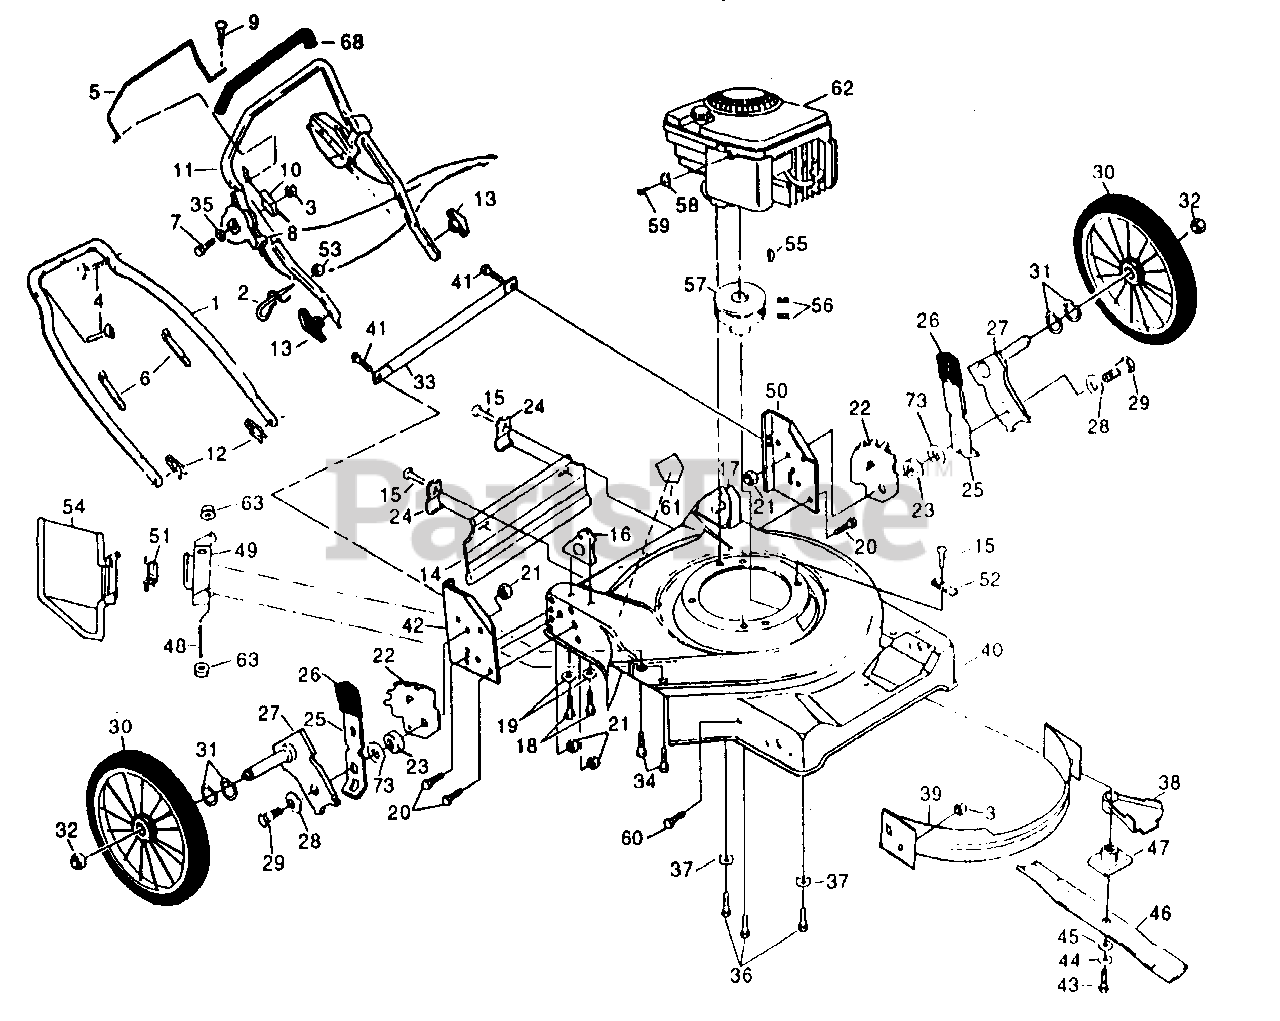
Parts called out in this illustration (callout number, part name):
1	Lower Handle (AYP part number)
2	Rope Guide
3	Locknut 1/4-20 (AYP part number)
4	Handle Bolt (AYP part number)
5	Control Bar (AYP part number)
6	Wire Tie (AYP part number)
7	Machine Screw 1/4-20 x 2-1/4 (AYP part number)
8	Throttle Control
9	Pan Head Hi/Lo Screw #10-16 x .63 (AYP part number)
10	Engine Zone Cable
11	Upper Handle (AYP part number)
12	Hairpin Cotter (AYP part number)
13	Handle Knob (AYP part number)
14	Rear Skirt (AYP part number)
15	Hex Head Screw #10 (AYP part number)
16	Handle Bracket Assembly (Right) (AYP part number)
17	Handle Bracket Assembly (Left) (AYP part number)
18	Screw 5/16-18 x 3/4 (AYP part number)
19	Washer (AYP part number)
20	Bolt, Hex Head 3/8-16 x 3/4 (AYP part number)
21	Locknut (AYP part number)
22	Wheel Adjusting Bracket (R.R.) (AYP part number)
23	Spacer (AYP part number)
24	Skirt Bracket (AYP part number)
25	Selector Spring (AYP part number)
26	Selector Knob
27	Axle Arm Assembly (AYP part number)
28	Rear Spring Washer (AYP part number)
29	Shoulder Bolt 3/8-16 (AYP part number)
30	Wheel & Tire Assembly (Rear) (AYP part number)
31	Wave Washer (AYP part number)
32	Nut (AYP part number)
33	Rod Support (AYP part number)
34	Hex Head Thread Rolling Screw w/Sems 1/4-20 x 3 (AYP part number)
35	Flat Washer (AYP part number)
36	Thread Rolling Screw 3/8-16 x 1 (AYP part number)
37	Engine Washer (AYP part number)
38	Debris Shield
39	Front Baffle (AYP part number)
40	Mower Housing Kit (Inc. 61)
41	Screw (AYP part number)
42	Wheel Support Bracket R.H. (AYP part number)
43	Hex Head Screw 3/8-24 x 1-3/8 Gr. 8
44	Helical Washer 3/8 (AYP part number)
45	Hardened Washer (AYP part number)
46	22" Blade
47	Blade Adapter
48	Hinge Rod (AYP part number)
49	Housing Bracket (AYP part number)
50	Wheel Support Bracket L.H. (AYP part number)
51	Torsion Spring (AYP part number)
52	Guide Clip (AYP part number)
53	Locknut (AYP part number)
54	Discharge Guard
55	Hi-Pro Key (AYP part number)
56	Set Screw (AYP part number)
57	Engine Pulley (AYP part number)
58	Cable Clamp (AYP part number)
59	Screw #10 x 5/8 (AYP part number)
60	Screw (AYP part number)
61	Danger Decal (AYP part number)
63	Push Nut (AYP part number)
68	Handle Grip (AYP part number)
73	Flat Washer 3/8 (AYP part number)
